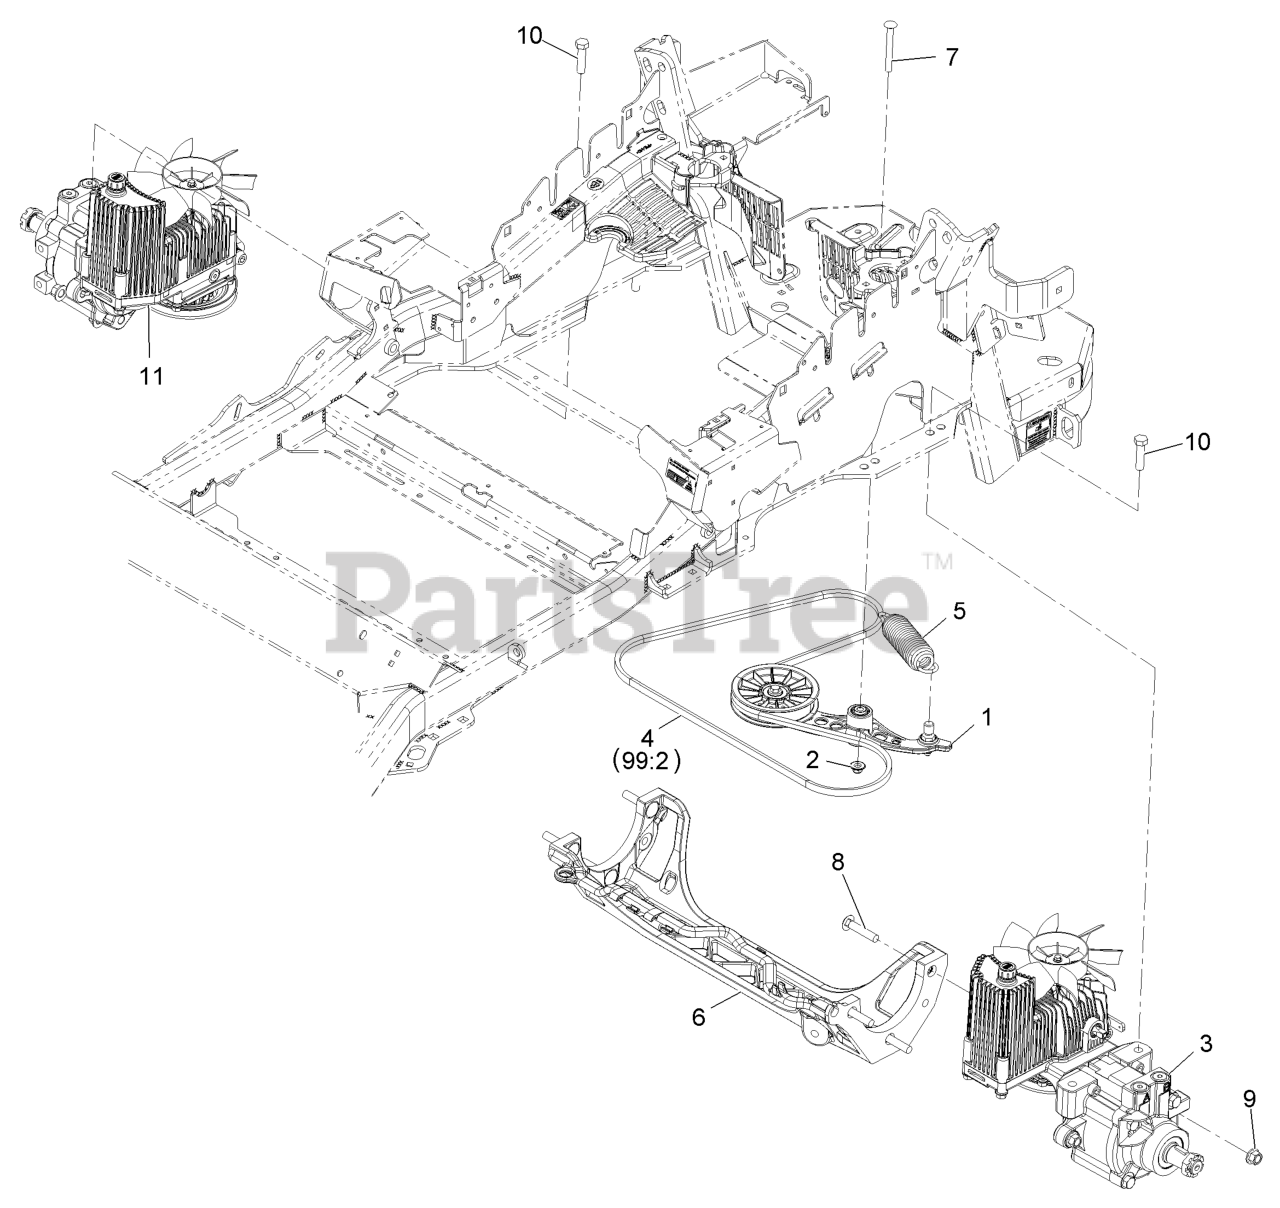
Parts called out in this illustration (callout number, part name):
1	PUMP IDLER ASM
2	Nut-Nyloc 3/8-16 Flg
4	BELT
5	SPRING-EXTENSION
7	BOLT-SHOULDER, CARRIAGE 3/8-16 X 3 1/2
8	SCREW-CARR
9	Nut-Lock 1/2-13
10	SCREW-HH
99:2	BELT
